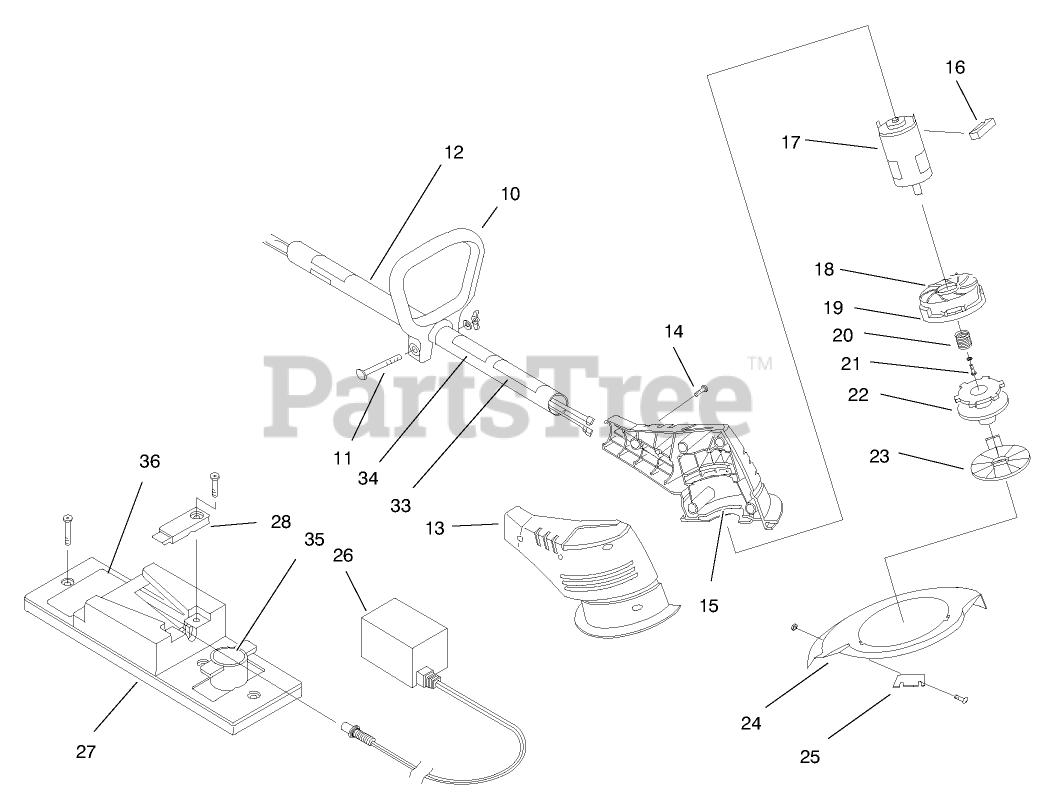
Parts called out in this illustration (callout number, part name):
10	D-HANDLE
11	HARDWARE - D-HANDLE
12	ASSEMBLY - BOOM
13	HOUSING - MOTOR
14	SCREW - HOUSING
15	SUPPORTS - MOTOR (3)
16	BLOCK - ANTI-ROTATION
17	MOTOR
18	Outer Spool and Eyelet (Incl. Ref. #19)
19	EYELET
20	SPRING
21	SCREW & WASHER
22	Inner Reel and .065 Line (15 ft.)
23	COVER - REEL
24	Guard and Blade Assembly (Inc. Ref. #25)
25	ASSEMBLY - BLADE
26	CHARGER - BATTERY
27	ASSEMBLY - WALL STATION
28	WALL STATION CLAMP/SCREW
33	Decal-Safety Symbol
34	DECAL - UL SAFETY WARNING
35	DECAL - TORO LOGO
36	Decal-Caution
